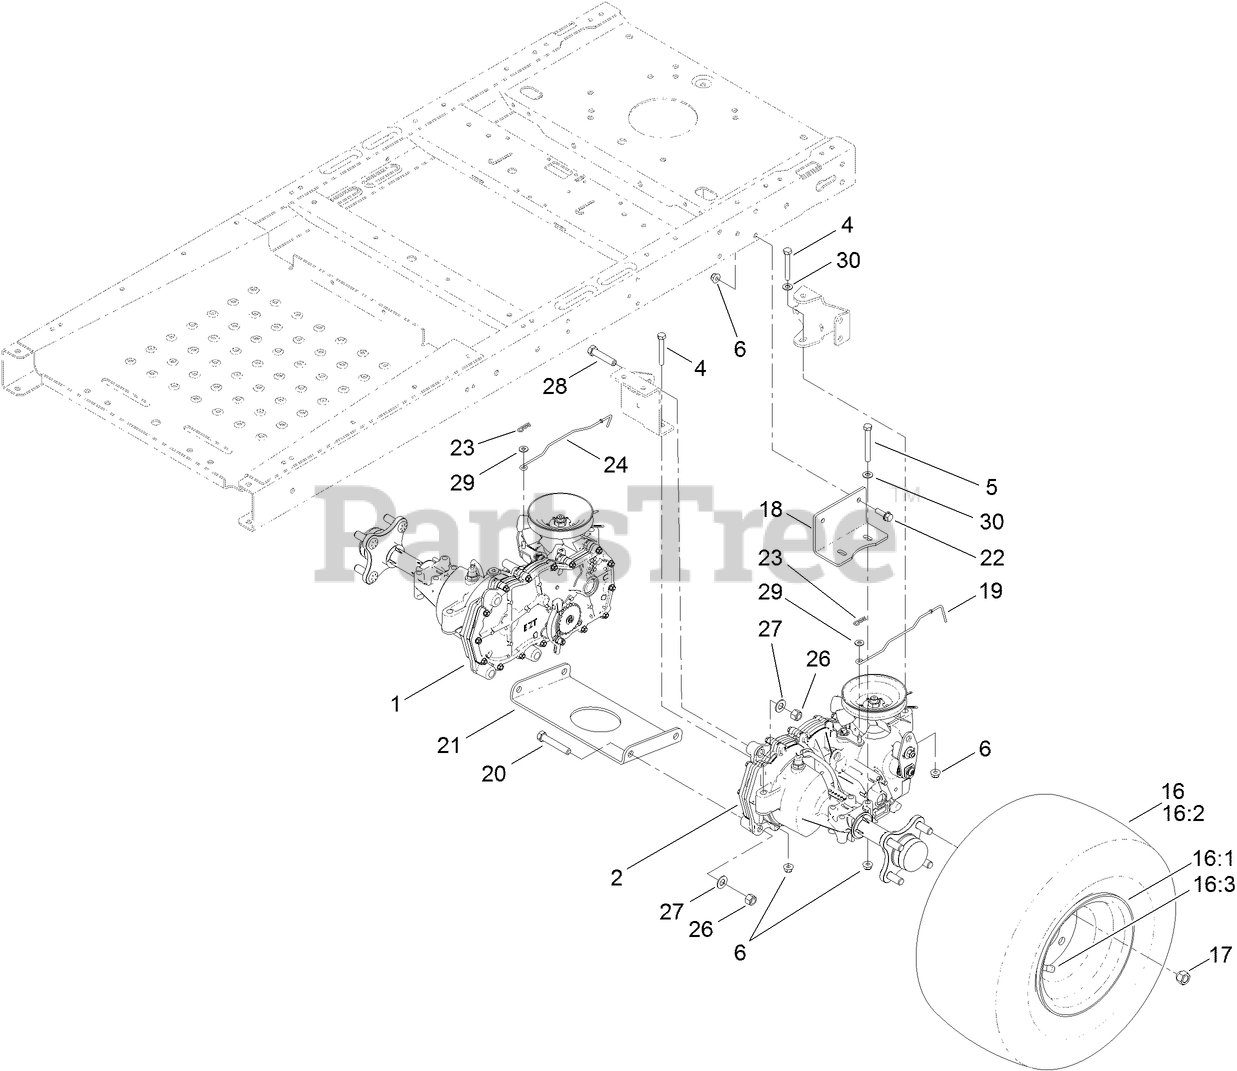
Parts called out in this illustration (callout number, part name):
1	RH HYDRO TRANSAXLE ASM
2	LH HYDRO TRANSAXLE ASM
4	SCREW-HH
5	SCREW-HH
6	NUT-HF, NI
16	4 PLY WHEEL AND TIRE ASM
16:2	TIRE-4 PLY
17	NUT-LUG
18	MOUNT-HYDRO
19	ROD-BYPASS, LH
20	SCREW-HH
21	PLATE-CROSS, HYDRO
22	SCREW-HHF
24	ROD-BYPASS, RH
26	NUT-LOCK, NI
27	WASHER-FLAT
28	SCREW-HH
29	WASHER-FLAT
30	WASHER-PLAIN
